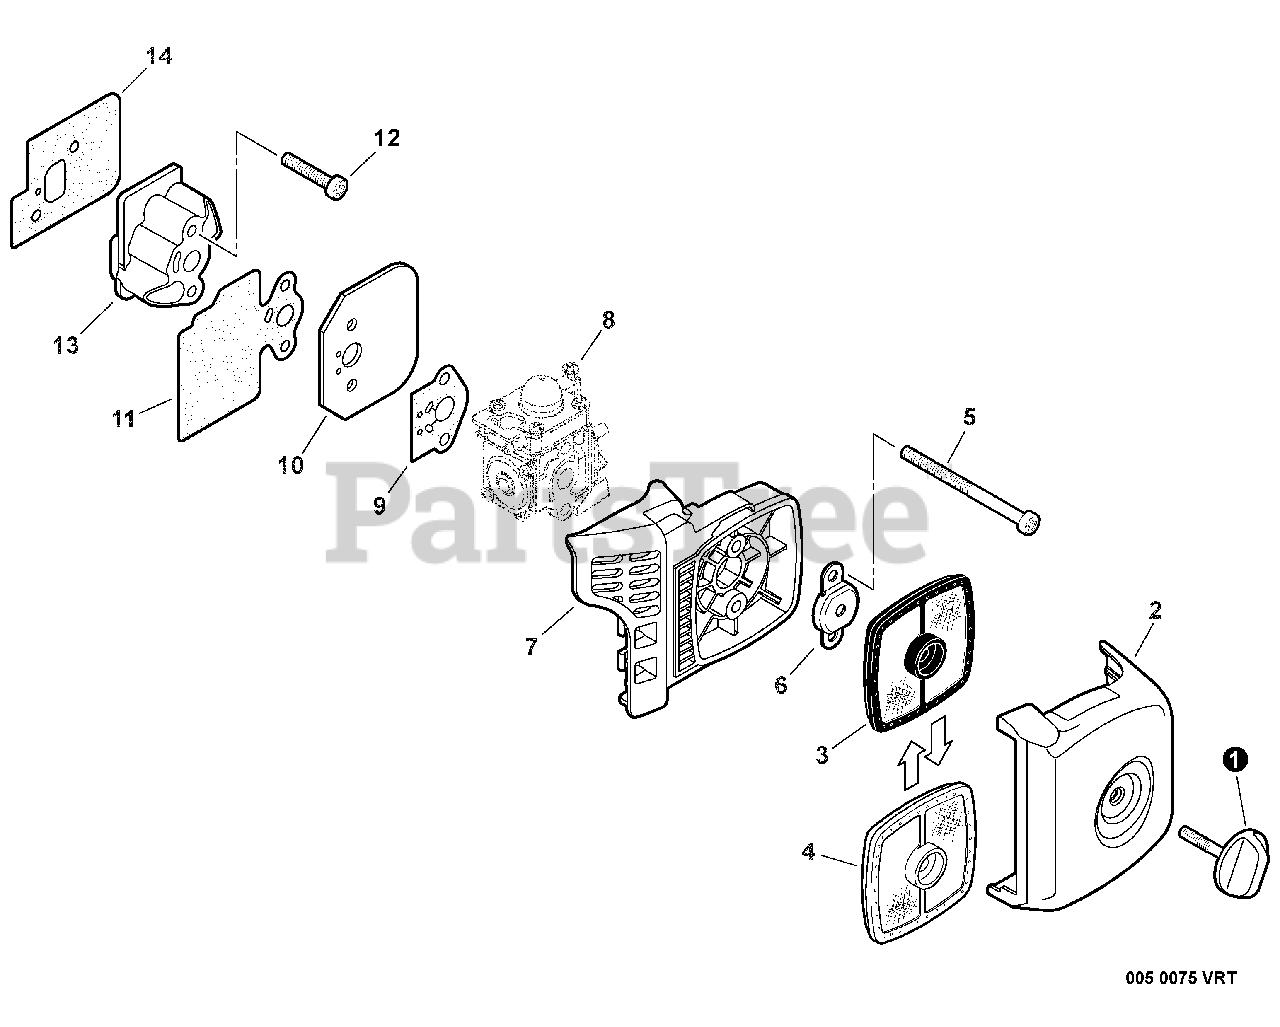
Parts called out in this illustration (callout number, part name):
1	THUMBSCREW
2	COVER, AIR FILTER
3	FILTER, AIR - DOUBLE LAYER
4	FILTER, AIR - SINGLE LAYER
5	SCREW - 5X65
6	PLATE, PREVENT
7	CASE, AIR FILTER
8	CARBURETOR
9	GASKET, INTAKE
10	PLATE, INSULATOR
11	GASKET, INTAKE
12	SCREW - 5X25
13	INSULATOR, INTAKE
14	GASKET, INTAKE
